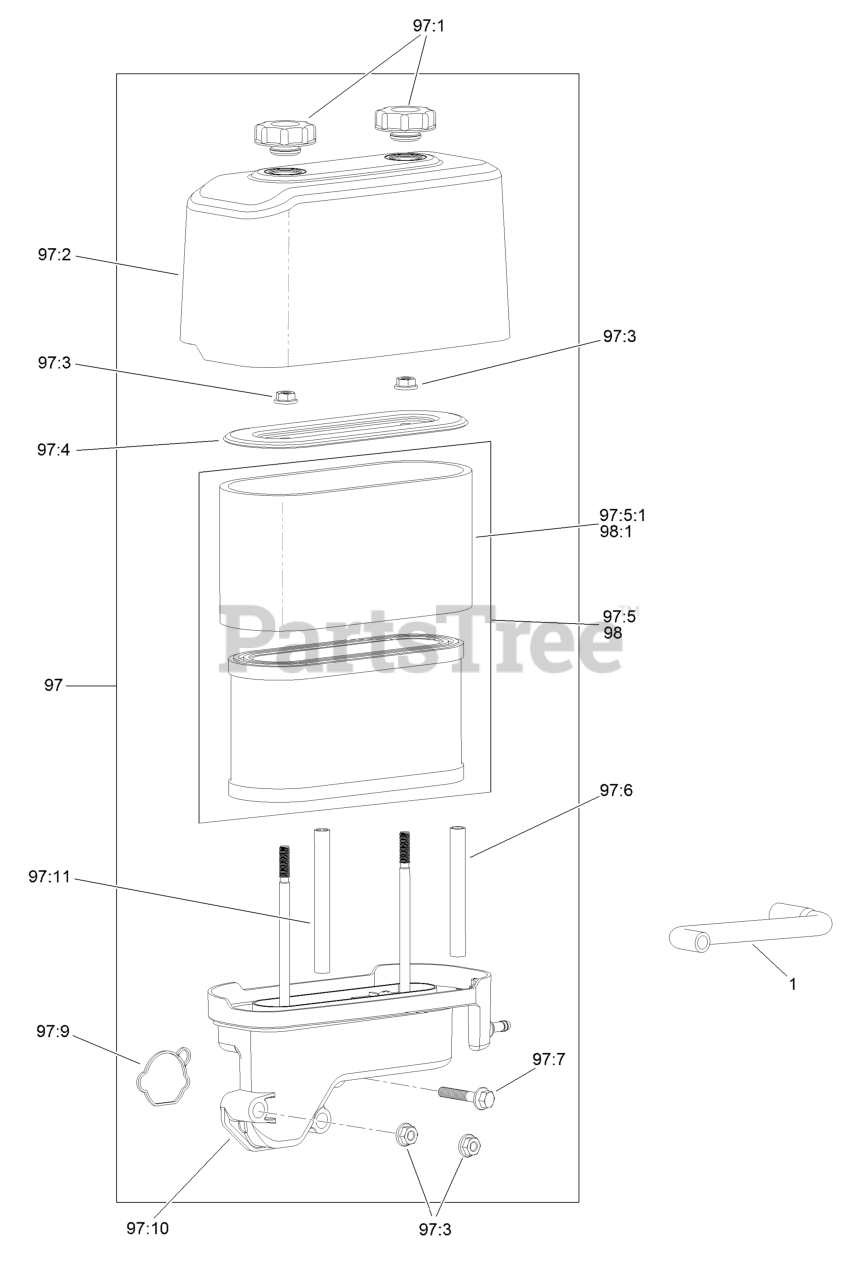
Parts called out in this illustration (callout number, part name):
1	TUBE-BREATHER
97:1	NUT-SPEED
97:2	COVER-FILTER, AIR
97:3	NUT-FLANGE
97:5:1	PREFILTER
97:6	SPACER-FILTER, AIR
97:7	SCREW-HHF
97:9	GASKET-CARBURETOR
97:11	SPACER-FILTER, AIR
98:1	PREFILTER
